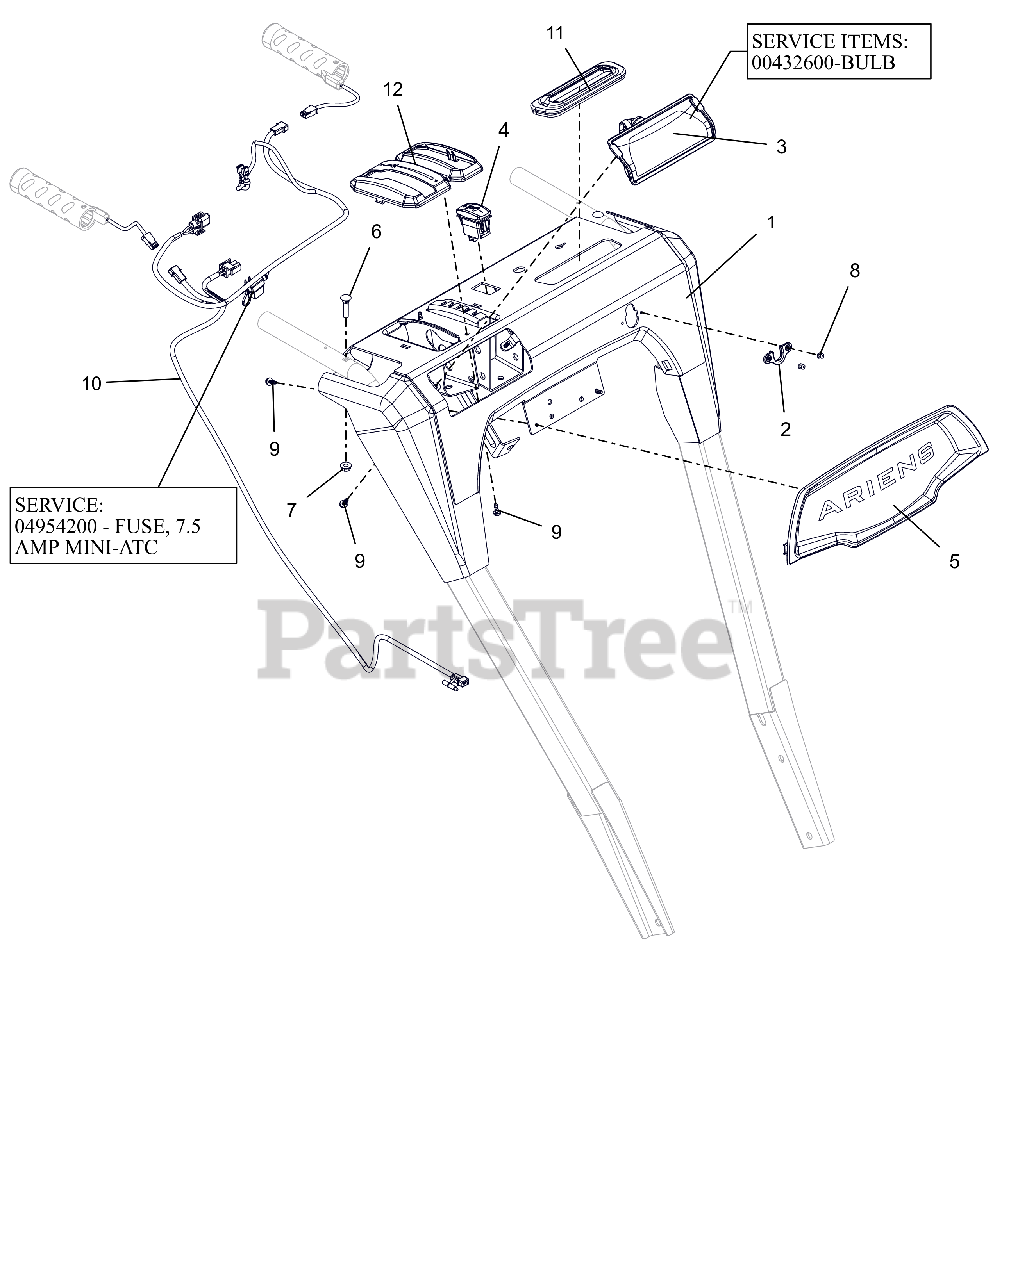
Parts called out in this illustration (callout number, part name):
1	PANEL, DASH-HYDRO EFI W/DECAL
2	GROMMET, CABLE, QUICK TURN 2
3	HEADLIGHT ASY, HALO 20W 2SHOT
3	BULB, LIGHT-HALOGEN 20W
4	SWITCH,ROCKER SPST-ON/OFF
5	BEZEL, DASH - ARIENS LG DASH
6	BLT-RDHDXLSQNK.25-20X1.25 G5ZC
7	NUT-LK-CTR-FLG .25-20 ZC120
8	RVT-POP #43 .125X.313 STL ZINC
9	SCR, PLASTIC #10X.50
10	HARNESS,LIGHT&WARMER - EFI
10	FUSE, 7.5 AMP MINI-ATC
11	GROMMET, BOOT, QUICK TURN
12	BEZEL, SHIFT - HYDRO SNOW
